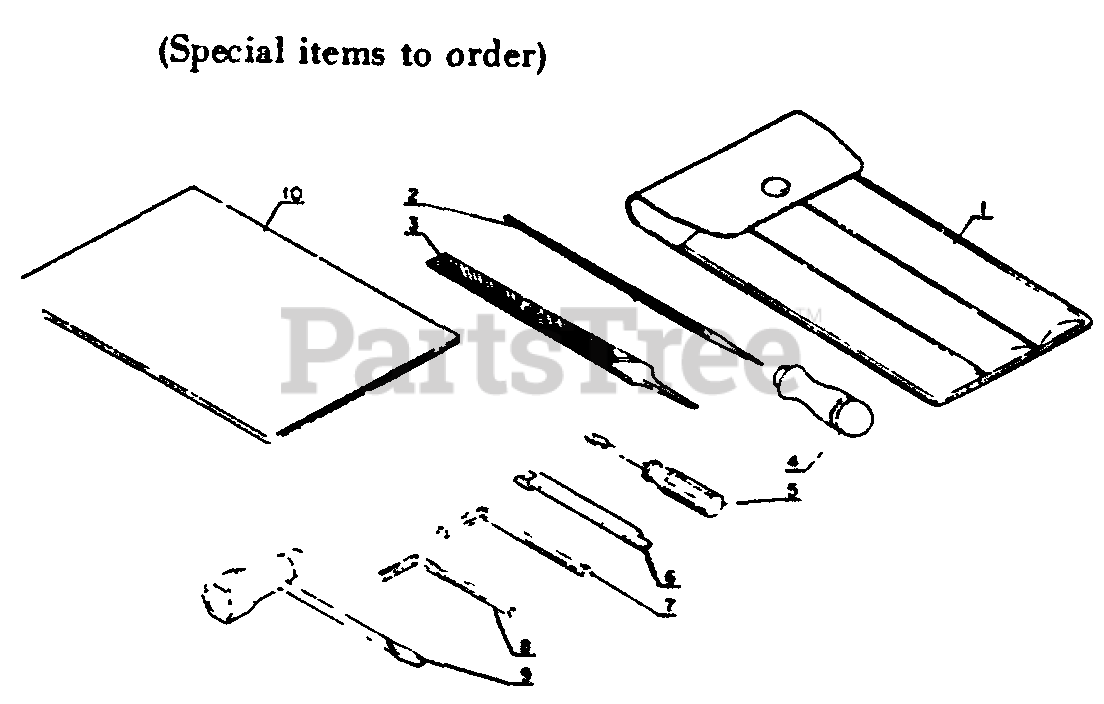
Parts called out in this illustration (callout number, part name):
1	BAG, TOOL
2	ROUND FILE
3	FLAT FILE
4	FILE GRIP
5	SCREWDRIVER - 50 MM
6	GAUGE, DEPTH
7	WRENCH, ALLEN 4 MM
8	L-WRENCH (3 MM)
9	T-WRENCH 10×19 MM
